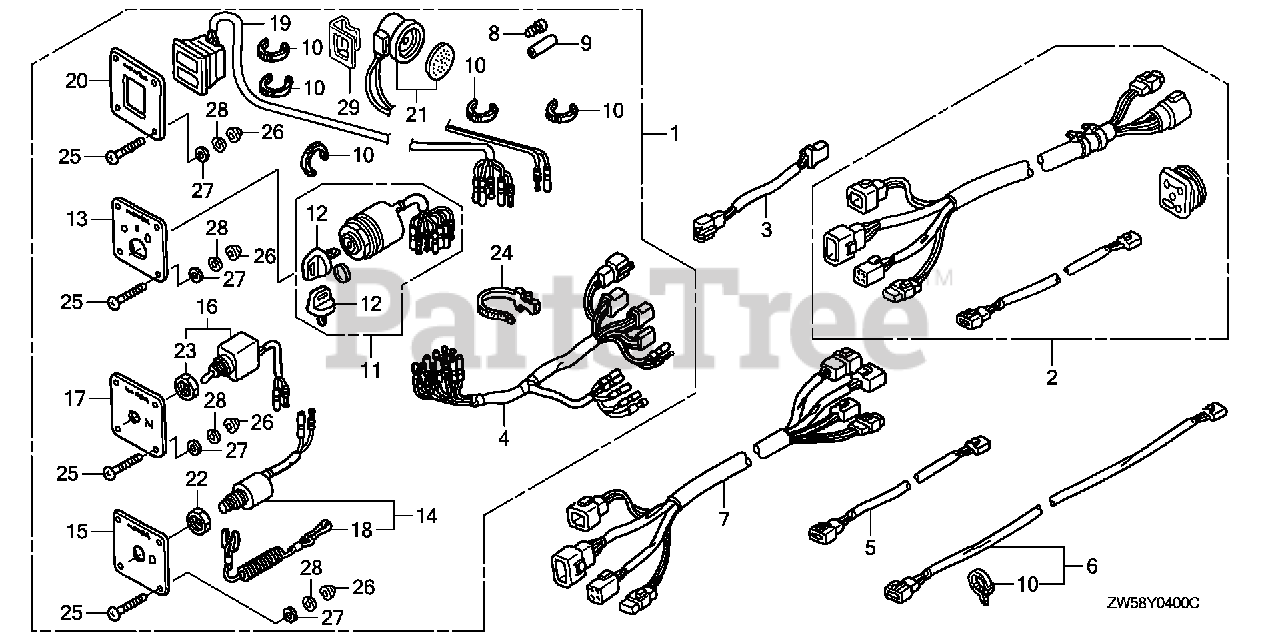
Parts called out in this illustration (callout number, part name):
1	PANEL KIT, CONTROL (B)
2	CABLE KIT, SWITCH INDICATOR
3	SUB-HARNESS ASSY., POWER TRIM-TILT (A)
4	HARNESS ASSY., SWITCH PANEL
5	CABLE ASSY., EXTENSION (3P 7FT)
6	CABLE ASSY., EXTENSION (3P 30FT)
7	CABLE ASSY., EXTENSION (17P 7FT)
8	PLUG, CONNECTOR (INNER)
9	PLUG, CONNECTOR (OUTER)
10	TIE, CABLE (2.4X92) (NATURAL)
11	SWITCH ASSY., COMBINATION
12	KEY ASSY., COMBINATION SWITCH (35100-ZV5-003 ONLY)
13	PANEL, SWITCH
14	SWITCH ASSY., EMERGENCY STOP
15	PANEL, EMERGENCY STOP SWITCH
16	SWITCH ASSY., SOLENOID
17	PANEL, SOLENOID
18	WIRE, EMERGENCY
19	LAMP ASSY., INDICATOR (2-LED)
20	PANEL, INDICATOR
21	BUZZER, WARNING
22	NUT, HEX. (16MM)
23	NUT, HEX. (12MM)
24	BAND, WIRE HARNESS (150MM) (NATURAL)
25	SCREW, PAN (5X40)
26	NUT, FLANGE (5MM)
27	WASHER, PLAIN (5MM)
28	WASHER, SPRING (5MM)
29	BRACKET, BUZZER
